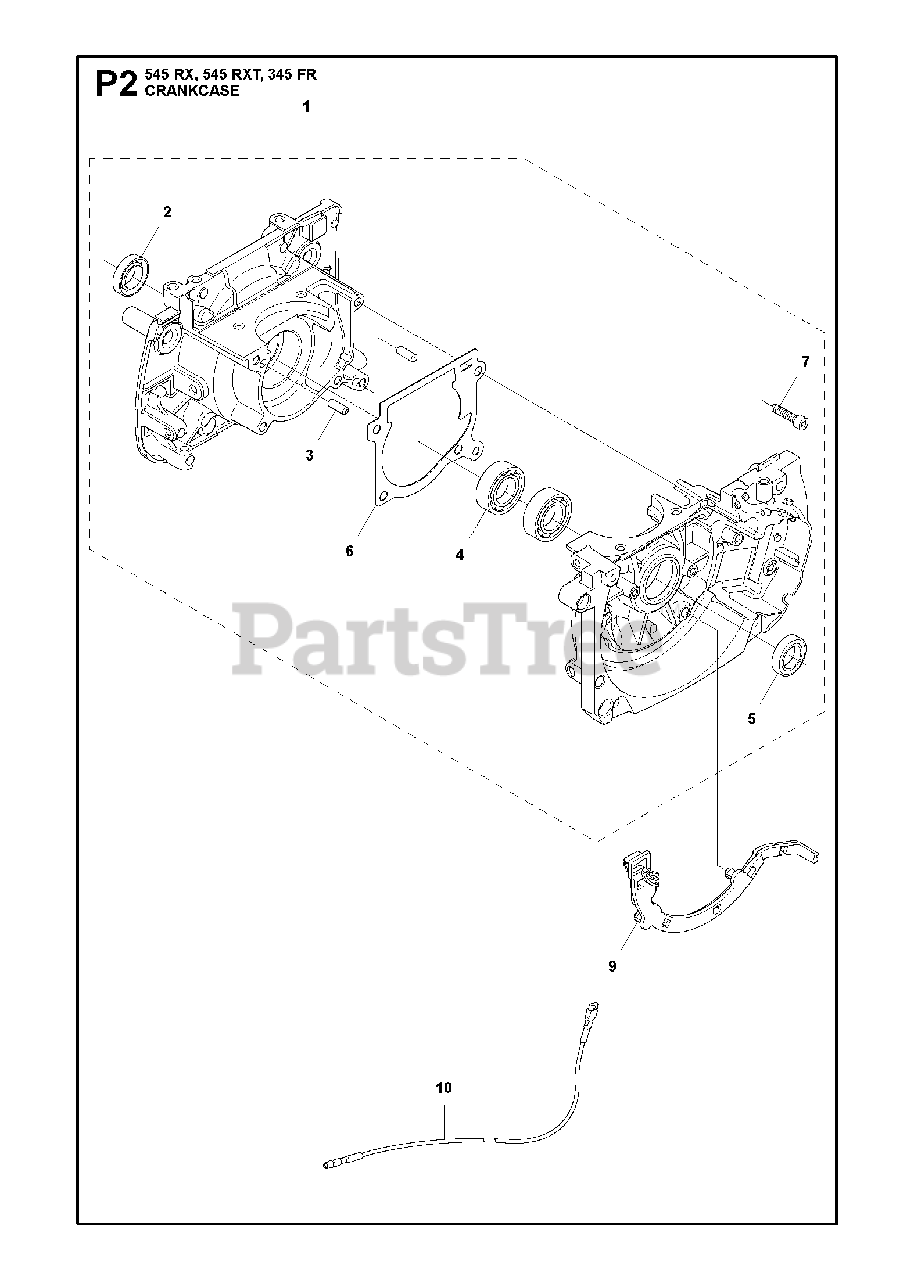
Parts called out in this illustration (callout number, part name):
1	CRANKCASE
1	CRANKCASE ASSY SPARE PART KIT
2	RADIAL SEAL
3	PIN 5X14
3	SLEEVE
4	BALL BEARING
5	SEAL RING
6	GASKET
6	GASKET CRANKCASE
7	SCREW MC6S 5X25
9	CABLE HOLDER
10	SHORT CIRCUIT CABLE
